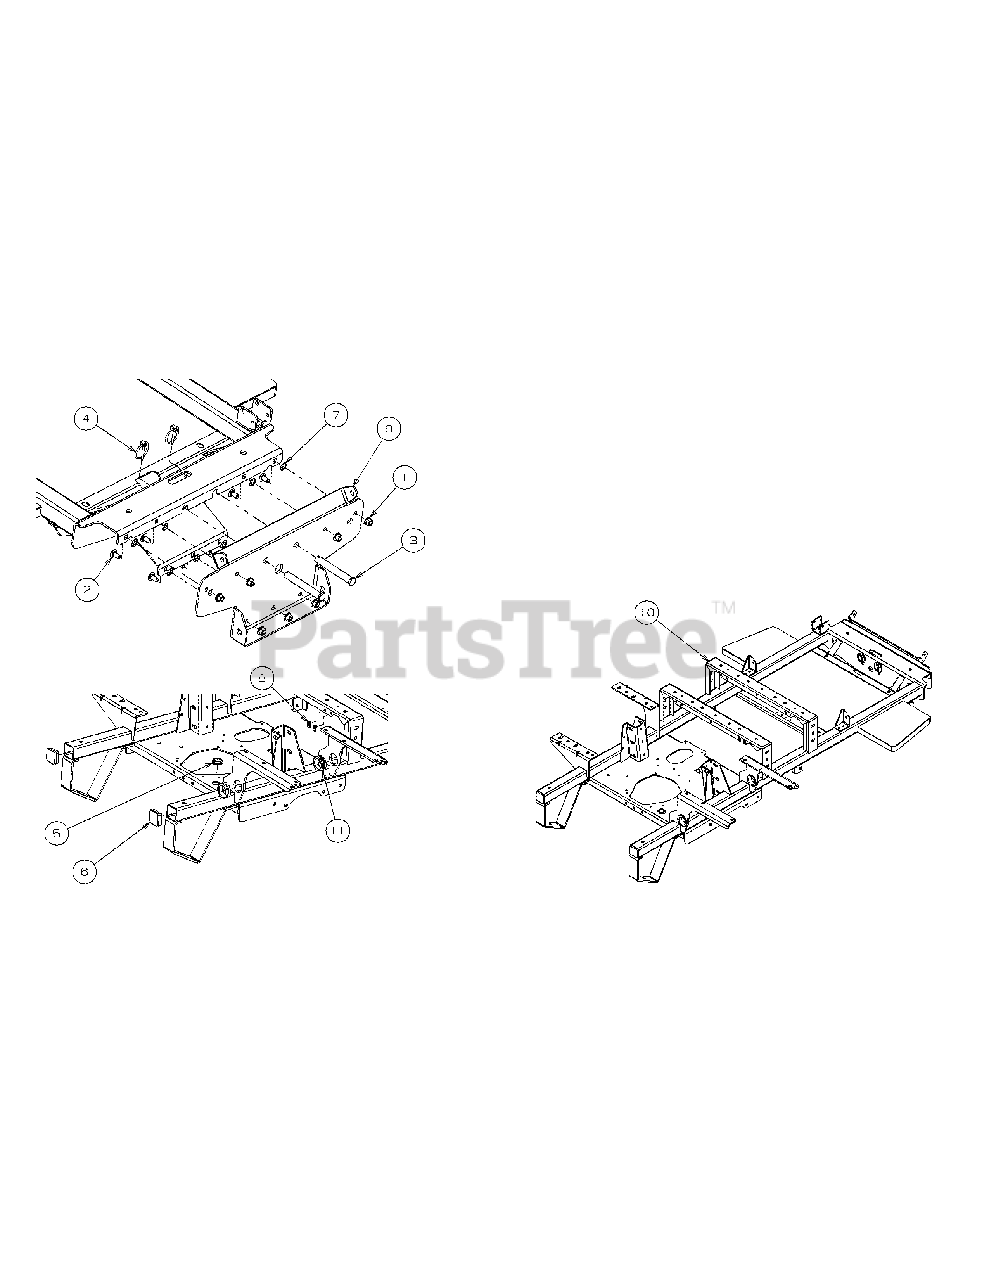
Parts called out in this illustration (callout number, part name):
1	Hex Nut, 3/8-16 Flange Lock
2	Carriage Bolt, 3/8-16 x .75 Long
3	Clevis Pin, .625 Dia x 4.375 Long
4	Linch Pin, 3/16 Dia.
5	Grom, .75 ID
6	Plug, Square Tube
7	Push Retainer, 3/8
8	U-Nut, 1/4-20
9	Bracket Assembly, Frame, Front
10	Frame Assembly
11	Rubber Grommet, 1.5 ID x 2.13 OD
